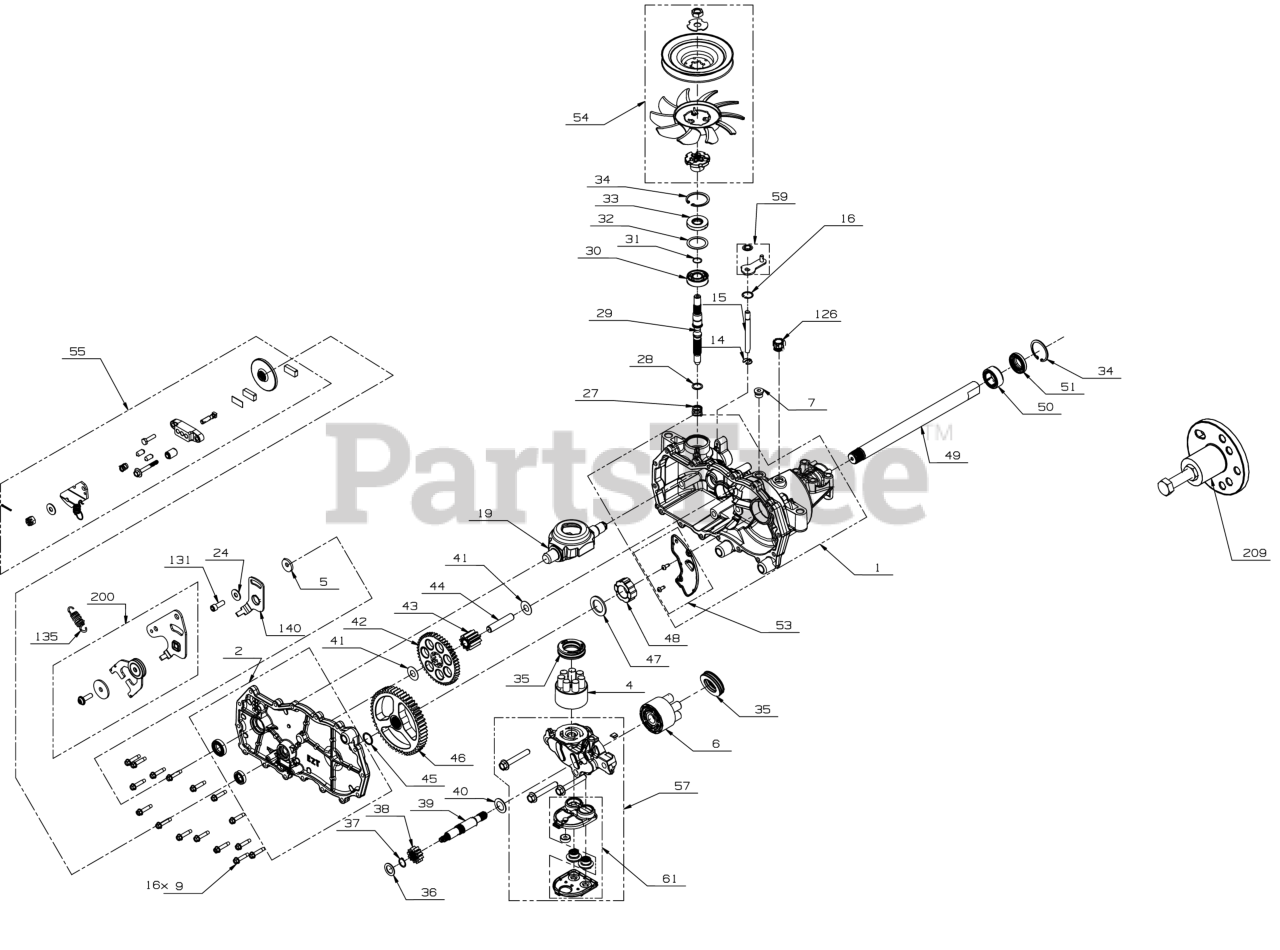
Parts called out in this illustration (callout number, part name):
1	HOUSING ASSEMBLY-MAIN
2	SIDE ASSEMBLY
4	BLOCK KIT-7 PISTON
5	SPACER .32 x 1.005 x .179
6	BLOCK KIT-5 PISTON
7	PLUG-STRAIGHT THRE
9	SCREW-WASHER HEAD
14	RETAINING RING
15	BYPASS RODS
16	RETAINING RING
19	SWASHPLATE-TRUNNION
24	FLAT WASHER
27	SPRING-BLOCK
28	THRUST WASHER
29	INPUT SHAFT
30	BALL BEARING
31	RETAINING RING
32	WASHER 1.23X1.56X
34	RETAINING RING
35	THRUST BEARING
36	FLAT WASHER
37	RETAINING RING
38	PINION GEAR 12T
39	MOTOR SHAFT
40	MOTOR SHAFT WASHER
42	GEAR 10T/49T
43	GEAR-10T JACKSHAFT
44	PIN-JACKSHAFT
45	RETAINING RING
46	GEAR-BULL 52T
47	WASHER 1.018 x 1.
48	SLEEVE BEARING
49	AXLE SHAFT
50	SLEEVE BEARING
53	PLATE KIT (RH) EXPANSI
54	KIT-FAN & PULLEY
55	BRAKE KIT-DISC
57	SECTION KIT-CENTER
58	SEALANT-HOUSING
59	ARM KIT-BYPASS
61	FILTER ASSEMBLY
126	BREATHER FITTING 9/16-18
131	SCREWS KIT-RTN
135	EXTENSION SPRING
140	ARM-NEUTRAL (LH)
200	RETURN KIT-NEUTRAL (LH) ZT2800 RZT
209	PULLER KIT-HUB
